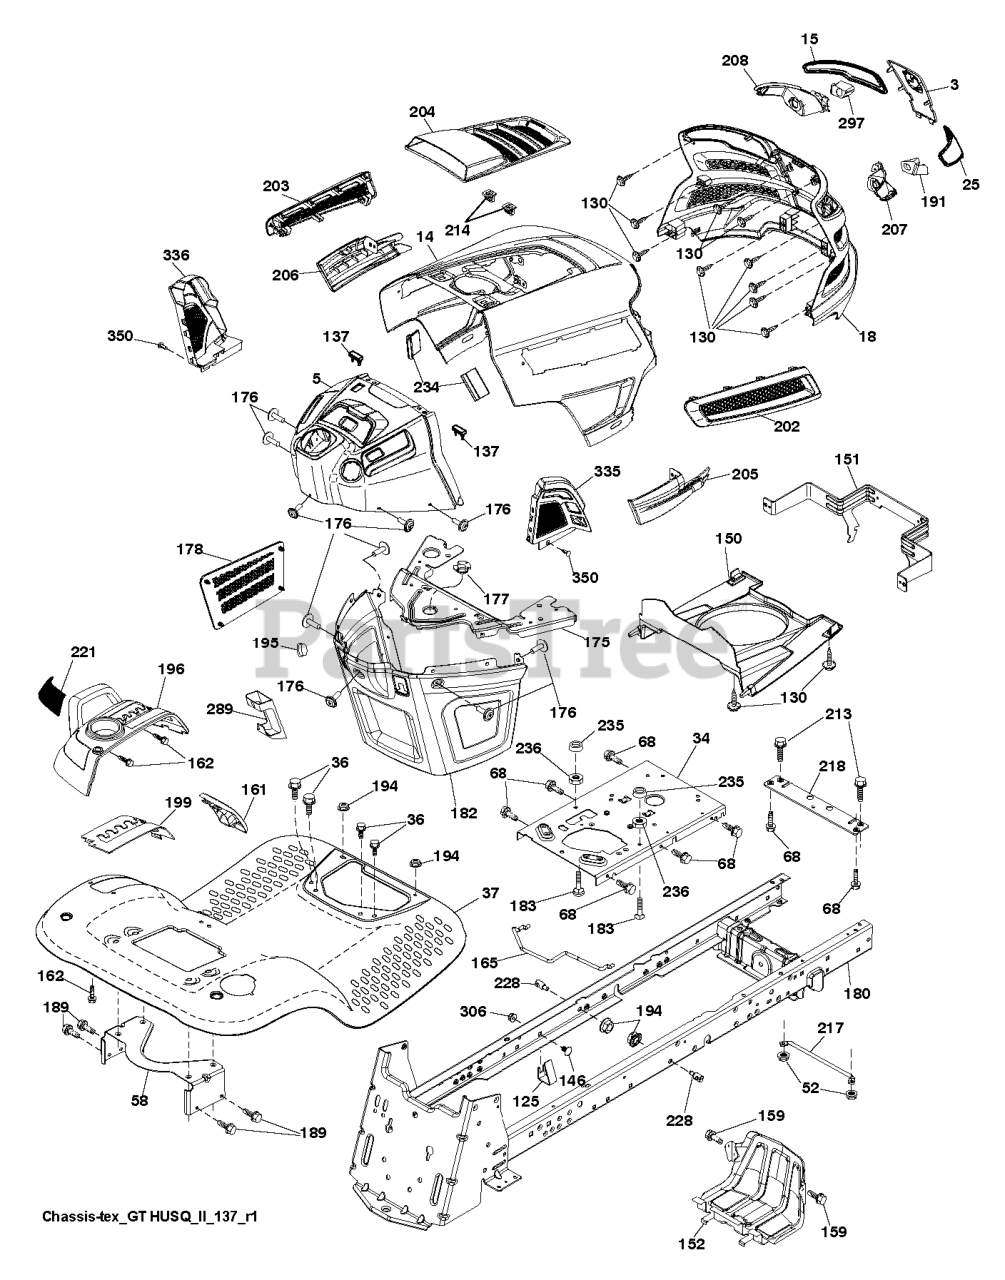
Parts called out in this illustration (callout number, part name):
3	APPLIQUE.SUBASM.GT.HUSQ.II
5	UPPER.ASSY.GT2.498.GRY
14	HOOD.ASM.HUSQVARNA.GT.TEX.ORAN
15	LENS.HEADLIGHT.LH.GTII.2011
18	GRILLE.SUBSTRATE.2011.
25	LENS.HEADLIGHT.RH.GTII.2011
34	PLATE.ENGINE.WELDED.CHASSIS
36	SCREW 5/16"
37	FENDER.PNT.TX.GT.CH/FW/DL.HUSQ
52	LOCKNUT
58	BRKT.SUPPORT.FNDR/TANK
68	Screw 5/16-18 x 1/2 Hex, Self Tapping 5/16-18 x 1/2
125	CLIP.FUEL.LINE
130	SCREW.#10 X 0.750.BOS
137	BUMPER DASH
146	BOLT.RDHD.SHT.SQNK.3/8-16X5/8
150	AIR.DUCT.GTV.BLACK
151	BRACKET.PIVOT.HOOD.GT.HUSQ.II
152	SHIELD.BROWNING.PNT.GT.V2
159	SCREW, 3/8-16X3/4
161	CONSOLE.WINDOW.FUEL.HUSQ.GT
162	SCREW.HI-LO.CONSOLE
165	SUPPORT.TANK.REAR.W/TEX
175	PLATE.CROSSMEMBER.HUSQ
176	SCREW.#10-24X5/8.RN.QU
177	BUSHING STEERING
178	CARGO.ASM.NET.TXGT.W/C
180	CHASSIS.GT.SLOPED.DRAWBAR.
182	DASH.LOWER.COMMON.12V.ADAPTOR
183	BOLT.5/16-18X1-1/4 FULL THD
189	SCREW
191	INSERT.REFLECTIVE.RH.HUSQ.GTII
194	NUT LOCK HEX FLANGE 5/16-18
195	PLUG.HOLE.DASH.LOWER.12V.BLK
196	SUBASM.CONSOLE.HUSQ.GT.DECKLFT
199	PLATE.DECK.LIFT.HUSQVARNA.GT
202	VENT.SIDE.RH.GT.HUSQ.II.
203	VENT.SIDE.LH.GT.HUSQ.II.498
204	VENT.TOP.HUSQ.GT2
205	SIDE.TRIM.RH.GT.HUSQ.II
206	SIDE.TRIM.LH.GT.HUSQ.II.GRAY
207	BEZEL LIGHT.RH.GT.II.MYLAR
208	BEZEL LIGHT.LH.GT.II.MYLAR
213	BOLT
214	CLIP.RETAINER.TINNER.
217	ROD.PIVOT.HOOD
218	X-PIECE.HOOD.STOP.NON/
221	REFLECTOR.LH.TEX GT HU
228	STUD.FASTNER.W/ANTI-ROTATE
234	BUMPER.HOOD.TEX.HUSQVARNA
235	SPACER FENDER
236	NUT.CENTERLOCK.5/16-
289	PLUG.N/CRUISE.COMMON.YT/GT.BLK
297	INSERT.REFLECTIVE.LH.HUSQ.GTII
306	NUT LOCK FLG 3/8-16 UNC
335	COVER.LOWER.DASH.RH.BLACK
336	COVER-LH.LOWER.DASH.GT2.BLACK
350	CLIP.X-MAS.TREE
